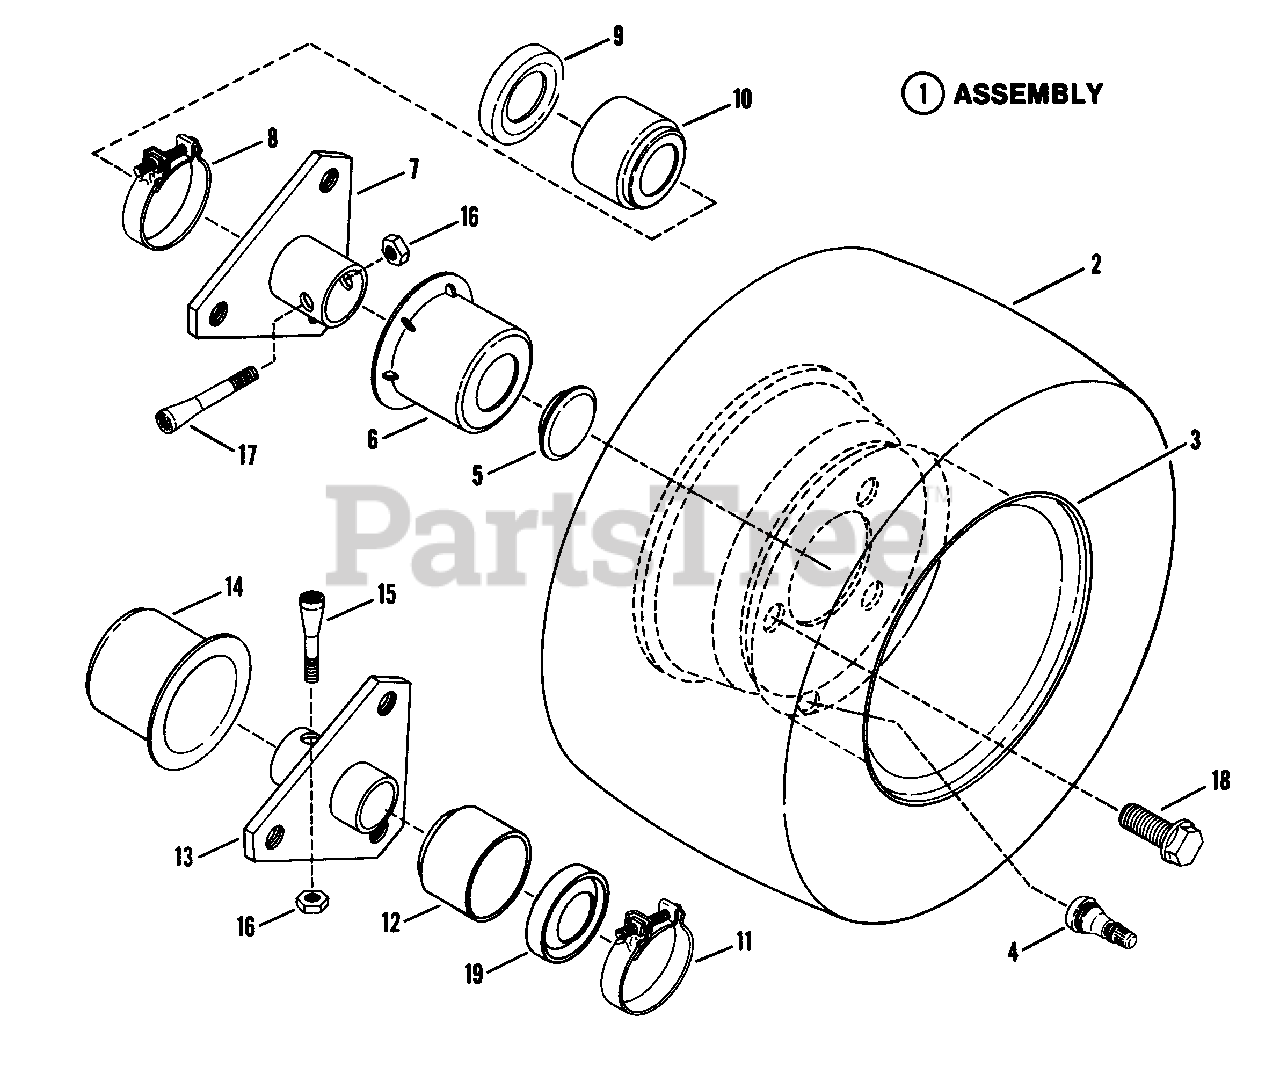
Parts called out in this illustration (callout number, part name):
1	ASSEMBLY, Rear Tire & Rim
2	TIRE, Wide, 16/6.50x8
3	RIM, Wide
4	VALVE, Air (Snap-in)
5	PLUG, Right Hand, Commercial
6	HUB-CAP, Right Hand, Commercial
7	HUB, Rear Wheel, Right Hand
8	CLAMP, Right Hand
9	SEAL, Oil, Right Hand
10	BOOT, Right Hand
11	Cl AMP, Left Hand
12	BOOT, Left Hand
13	HUB, Rear Wheel, Left Hand
14	HUB-CAP, Left Hand
15	BOLT, Tapered, Left Hand
16	NUT, 5/16-24 Lock
17	BOLT, Tapered, Right Hand
18	BOLT, Lug
19	SEAL, Oil, .75" ID, 1.832" OD, .25" Thick, Left Hand
